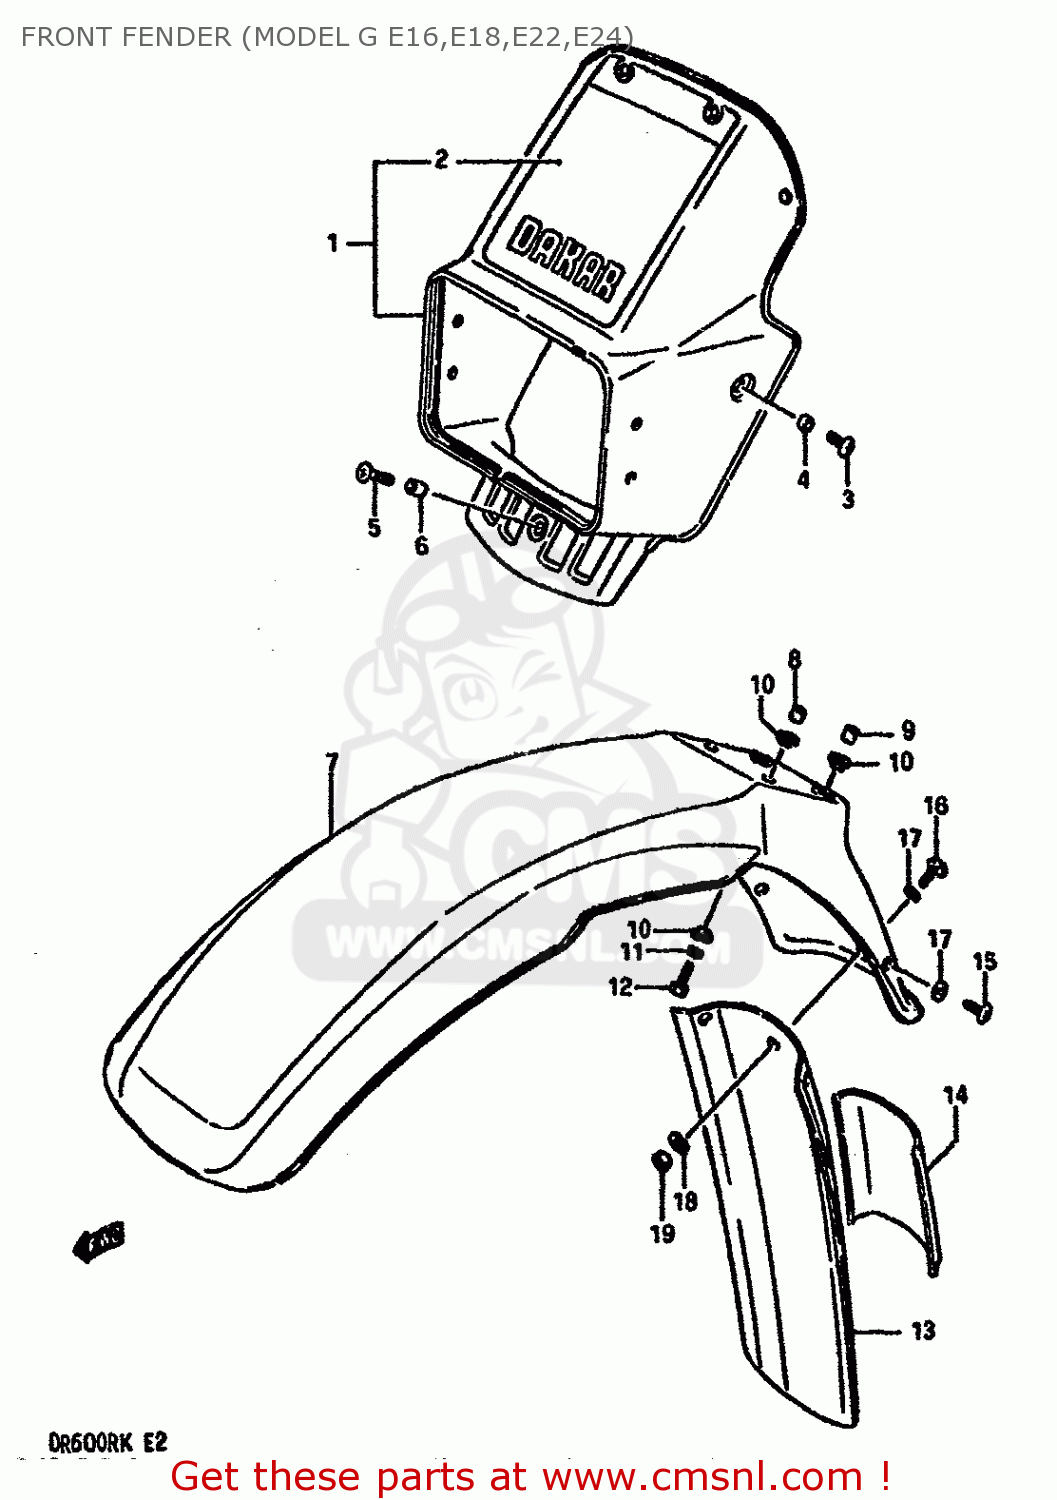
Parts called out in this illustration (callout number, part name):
1	COVER, HEADLAMP (WHITE)
2	TAPE SET
3	SCREW 6X12
4	SPACER (6.1X8X3.5)
5	SCREW, CENTER
6	SPACER (6.1X8X12)
7	FENDER,FRONT (WHITE)
8	SPACER(6.1X9X7.5)
9	SPACER (6.8X10X10)
10	WASHER
11	WASHER,LOCK
12	BOLT
13	MUD FLAP
14	PROTECTOR SEAT
15	SCREW
16	SCREW, CENTER
17	WASHER,LOCK
18	WASHER (6.7X16X1.8)
19	NUT 6MM
